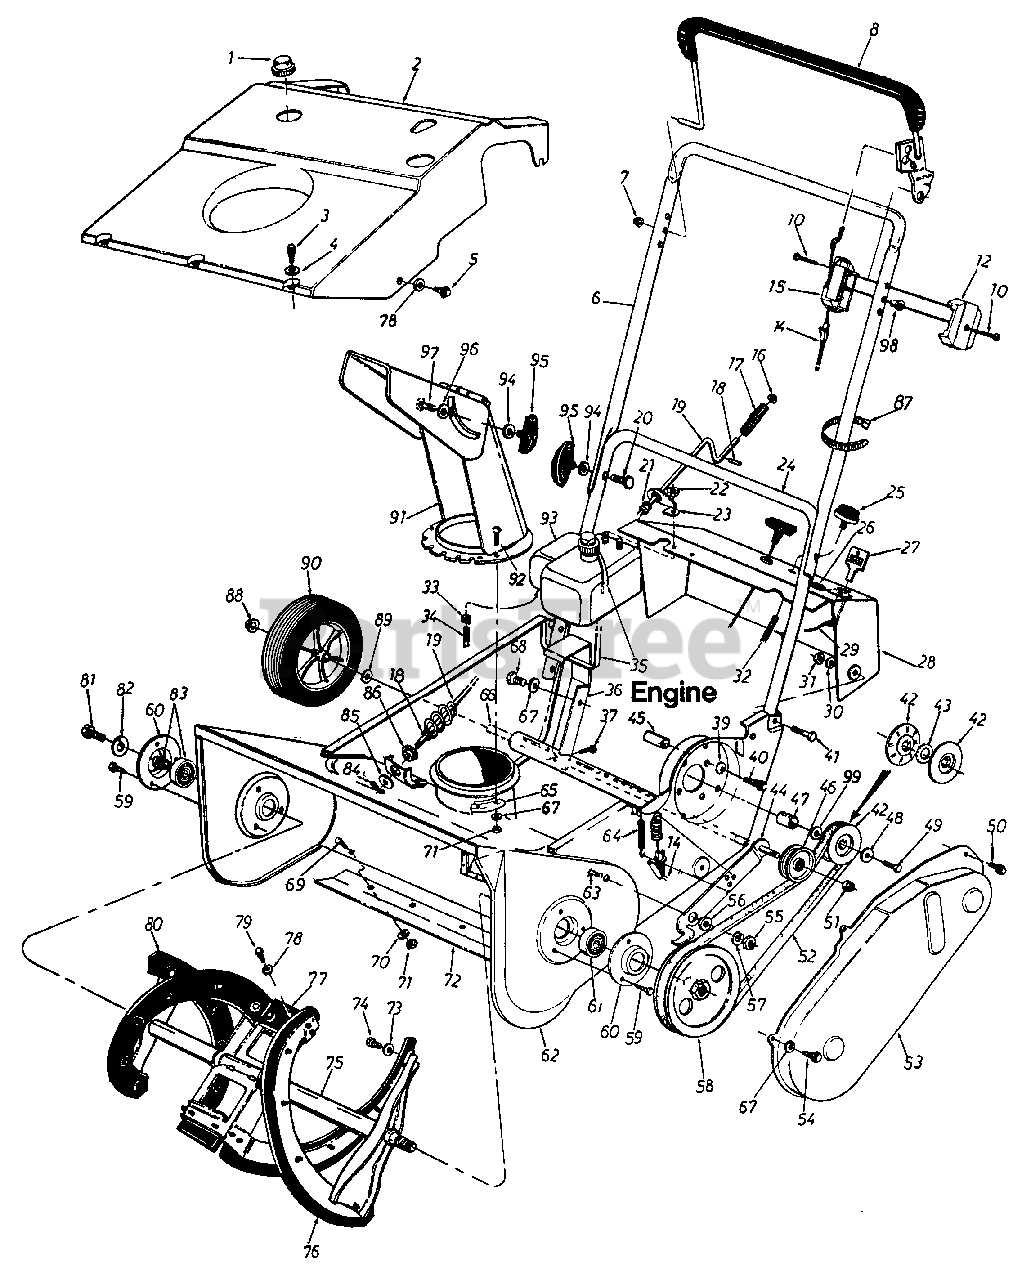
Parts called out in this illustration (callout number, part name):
1	Gas Tank Cap
2	21" Shroud
3	Hex B-Tap Scr. #10 x .38"
4	Spr.-Wash. .206" I.D. x .448" O.D.
5	Hex L-Wash. Hd. AB-Tap 1/4 x .62" Lg.
6	Upper Handle
7	Cap Speed Nut
8	Control Handle Ass'y.-L.H.
10	Truss Mach. Hi-B Tap Scr. #12 x 1.5" Lg.
12	Control Panel Half
14	Clutch Cable 35" Lg.
15	Clutch Panel Half
16	Push Cap 3/8" Rod
17	Knob-3/8" Dia. Hole
18	Roll Pin 1/8" Dia. x .63" Lg.
19	Chute Crank Ass'y.
20	Curved Carriage Bolt 5/16-18 x 1.75" Lg.
21	Chute Crank Grommet
22	Hex L-Nut 1/4-20 Thd.
23	Upper Chute Crank Brkt.
24	Lower Handle
26	Plastic Plug
27	Plastic Key
28	Dash Panel Ass'y.
29	Ignition Wire
30	L-Wash. 5/16" I.D.
31	Hex Nut 5/16-18 Thd.
32	Primer Hose-11" Lg.
33	Hose Clamp-.406" Dia.
34	Gas Line-9" Lg.
35	Cable Tie-17.75" Lg.
36	Engine Support Brkt.
37	Hex L-Wash. Hd. AB-Tap Scr. 1/4 x.62" Lg.
39	Bell-Wash. .345" I.D. x .88"
40	Hex Bolt 5/16-18 x 1.5" Lg.
41	Hex Bolt 5/16-18 x 1.5" Lg.
42	3/8" "V"-Pulley Half .625" I.D. x 6.0" O.D.
43	Fl-Wash. .635" I.D. x .93"
44	Idler Brake Brkt. Ass'y.
45	Spacer .325" I.D. x .625" O.D. x .875"
46	Fl-Idler w/Flanges 2.12" O.D.
47	Spacer .635" I.D. x .89" O.D. x .57"
48	Bell-Wash. .345" I.D. x .88"
49	Hex Bolt 5/16-24 x .75" Lg.
50	Hex L-Wash. Hd. AB-Tap Scr. 1/4 x .62" Lg.
51	Hex Patch L-Nut 3/8-24 Thd.
52	V-Belt
54	Hex B-Tap Scr. 1/4" x .38"
55	Hex Nut 5/16-18 Thd.*
56	Shld. Spacer .50" Dia. x .27" Lg.
57	L-Wash. 5/16" I.D.*
58	1/2" "V"-Pulley 1/2-20 LH. x 6" O.D.
59	Hex B-Tap Scr. 1/4" x .38"
60	Bearing Cup
61	Ball Brg. .669" I.D. x 1.574"
62	21" Blower Hsg. Ass'y.
63	Truss Mach. Scr. 5/16-18 x .75" Lg.*
64	Extension Spring-.33" O.D. x 1.12" Lg.
65	Chute Flange Keeper
66	Wheel Axle Tubing
67	Fl-Wash. 1/4" I.D.
68	Hex Wash. S-Tap Scr. 1/4-20 x.50" Lg.
69	Carriage Bolt 1/4-20 x .62"*
70	Fl.-Wash. .281" I.D. x .73"
71	Hex L-Nut 1/4-20 Thd.
72	Shave Plate
73	Fl-Wash. .281" I.D. x .50"
74	Hex Wash. B-Tap Scr. 1/4 x .62"
75	Auger Ass'y. 21"
76	Rubber Spiral-L.H.
77	Rubber Paddle
78	Fl-Wash. .218" I.D. x .62"
79	Self Clinching Scr. 1/4-20- 0 5/8" Lg.
80	Rubber Spiral-R.H.
81	Hex Wash. TT-Tap Cl-Scr. 1/4-20 x .75" Lg.
82	L-Wash. 1/4" I.D.*
83	Kit-Bearing and Collar
84	Cotter Pin 3/32" Dia. x .75"
85	Fl-Wash. .390" I.D. x 1.50"
86	Hex Bushing .385" I.D.
87	Cable Tie
88	Push Cap 1/2" Dia.
89	Fl-Wash. .510" I.D. x .75"
90	Wheel & Tire Ass'y. 6 x 1.5
91	5" Dia. Chute Ass'y.
92	Truss Mach. Scr. 1/4-20 x .75"*
93	Fuel Tank-Two Qt.
94	Bell-Wash. .345" I.D. x .88"
95	Knob Handle Ass'y.
96	Fl-Wash. .328" I.D. x .68"
97	Carriage Bolt 5/16-18 x .62"*
98	Control Disc Pin
99	3 HP 110V Electric Start
